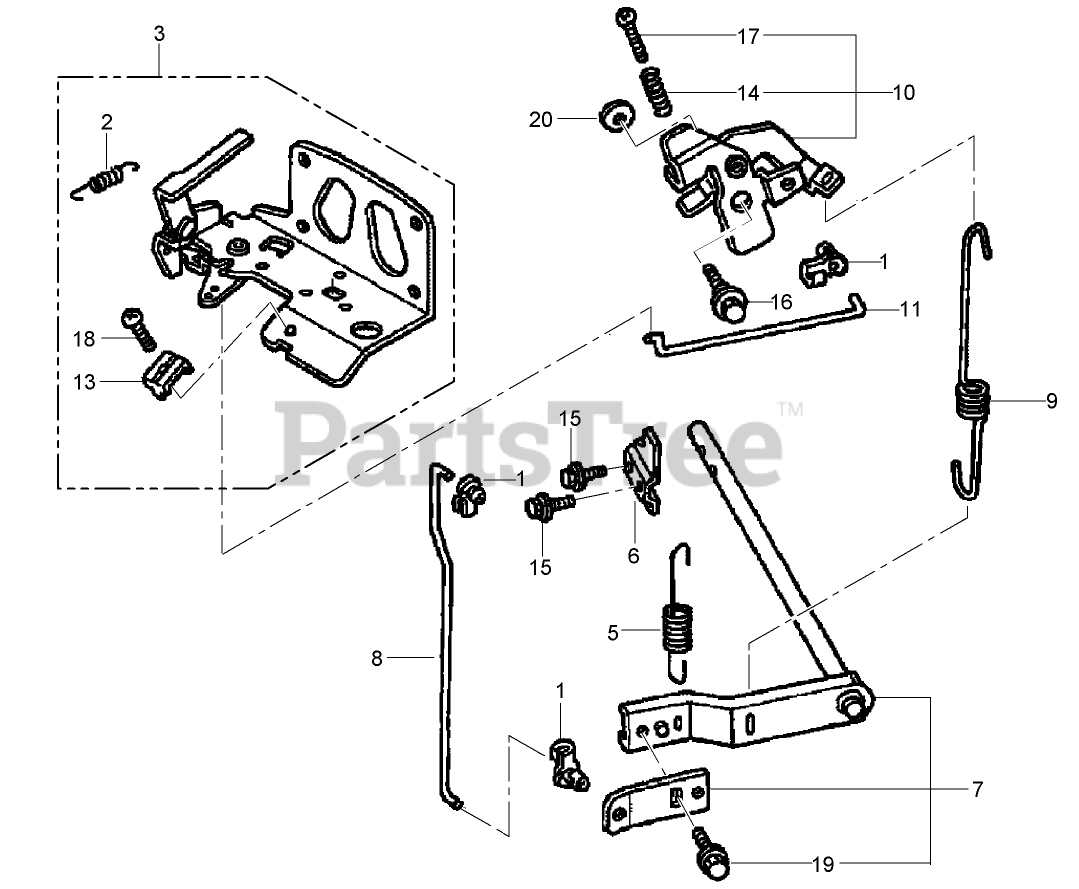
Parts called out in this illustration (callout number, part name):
1	ROD-JOINT
2	SPRING-RETURN, CHOKE
3	CONTROL ASM (1-LEVER)
5	SPRING-STARTER (Up to Engine Serial No. 1014986)
5	SPRING-STARTER (From Engine Serial No. 1038646)
6	FORK-GOVERNOR
7	ARM-GOVERNOR
8	ROD-GOVERNOR
9	SPRING-GOVERNOR
10	LINK-GOVERNOR
11	ROD-LINK, GOVERNOR
13	Holder-Cable
14	SPRING-ADJUSTING, CONTROL
15	BOLT-FLANGE (5X10)
16	BOLT-FLANGE (6MM) (C T200)
17	SCREW-RECESSED (5X25)
18	SCREW-RECESSED (5X18)
19	Bolt-Flange (6X10)
20	WASHER-PLAIN (6MM)
